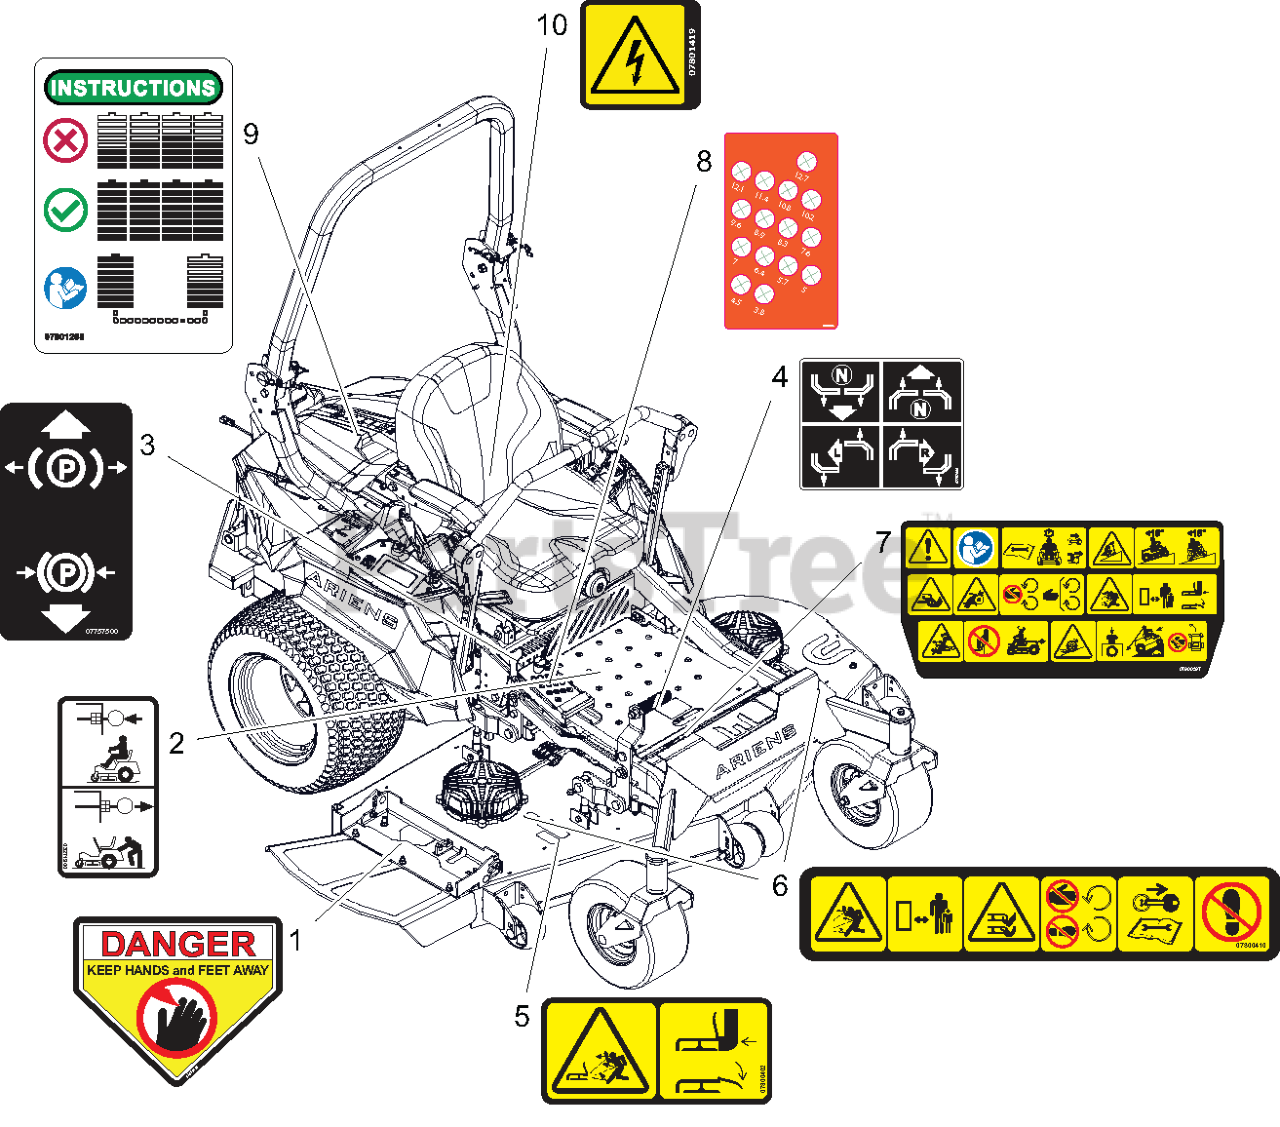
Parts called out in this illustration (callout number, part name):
1	DECAL, DANGER
2	DECAL, TRANSMISSION DISCONNECT
3	DECAL, PARKING BRAKE LEVER
4	DECAL, INSTRUCTIONAL-STEERING
5	DECAL, SAFETY - DECK GUARDING
6	DECAL, DECK SAFETY
7	DECAL, MAIN SAFETY
8	DECAL, APEX HOC METRIC
9	DECAL, BATTERY BALANCE
10	DECAL, SAFETY - DANGER
